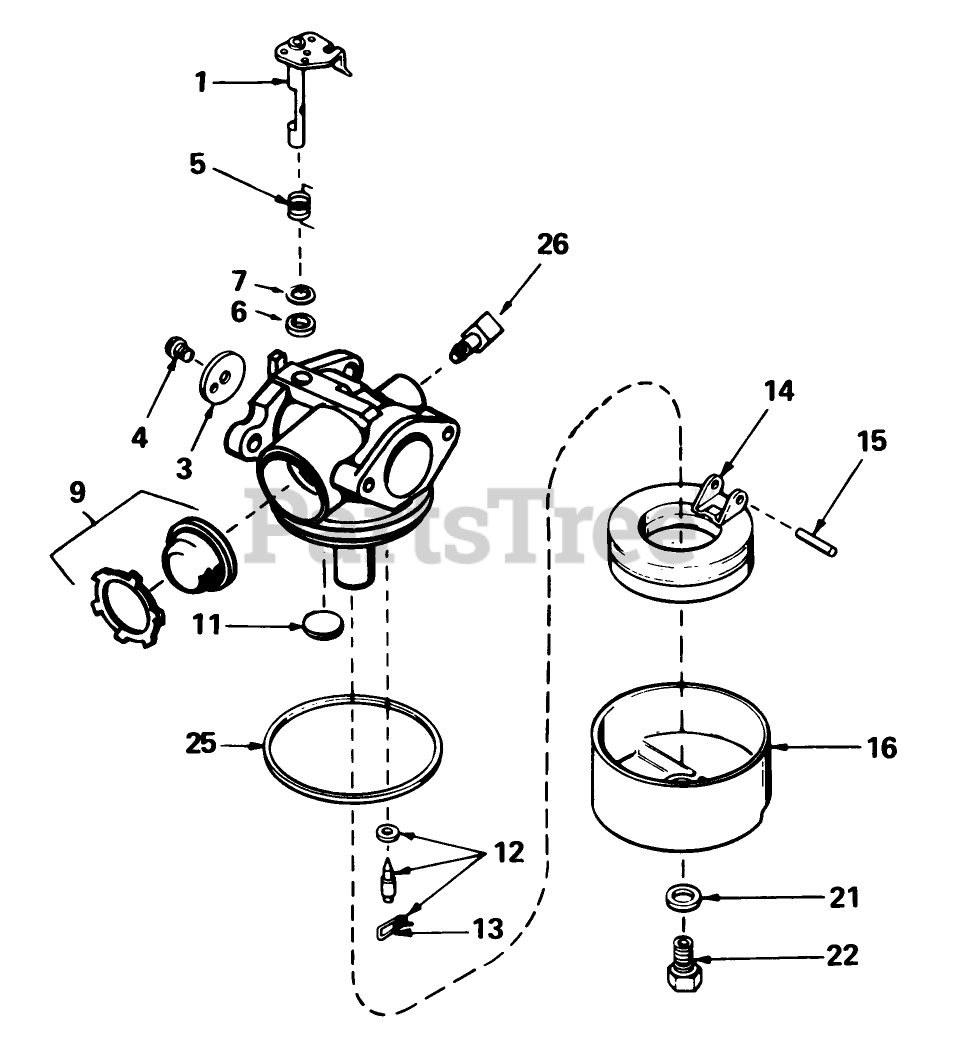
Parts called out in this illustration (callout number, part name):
1	Throttle Shaft and Lever ASM
3	Throttle-Shutter
4	Screw-Shutter
5	Spring-Return, Throttle
6	Seal-Dust
7	Washer-Seal, Dust
9	Primer Assy.
11	Plug-Welch, Atmospheric Vent
12	Inlet Needle, Seat Clip Assy. (Incl. No. 13)
13	Clip-Spring
14	Float
15	Shaft-Float
16	Bowl Float
21	Gasket-Bowl
22	Nut-Float Bowl
25	O Ring-Bowl, Float
26	Fitting-Fuel
